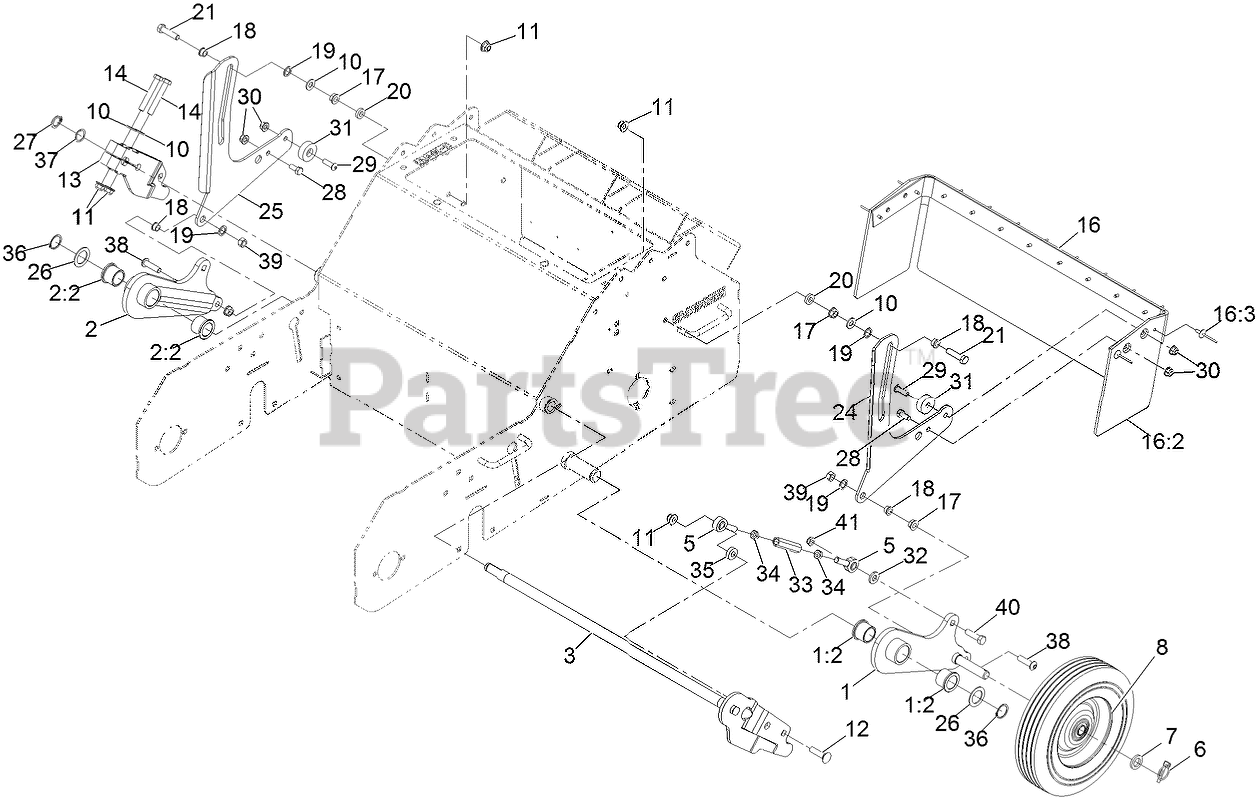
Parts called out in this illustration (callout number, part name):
1	LH WHEEL ARM ASM
1:2	BUSHING-FLANGE
2	RH WHEEL ARM ASM
2:2	BUSHING-FLANGE
3	PIVOT SHAFT ASM
5	BALLJOINT
6	PIN-KLIK
7	SPACER-BEARING
8	WHEEL, TRANSPORT
10	WASHER-FLAT
11	NUT-HF, NI
12	SCREW-CARR
13	ARM-LIFT, RH
14	SCREW-HH
16	GUARD-FOOT
16:2	FOOT-SHIELD
16:3	RIVET-POP
17	NUT-HHF, WHIZ
18	BUSHING-FLANGED
19	WASHER-NYLON
21	SCREW-HH
24	GUARD-ARM, LH
25	GUARD-ARM, RH
26	WASHER-SPACER
27	RING-RETAINING
28	SCREW-HH
29	SCREW-HSBH
30	NUT-HF, NI
31	GUIDE-ARM, TRAIL
33	ROD-LIFT LINK
34	NUT-HJ
35	SPACER
36	RING-RETAINING
37	WASHER-WAVE
38	SCREW-HSBH
39	NUT-HEX
40	SCREW-HH
